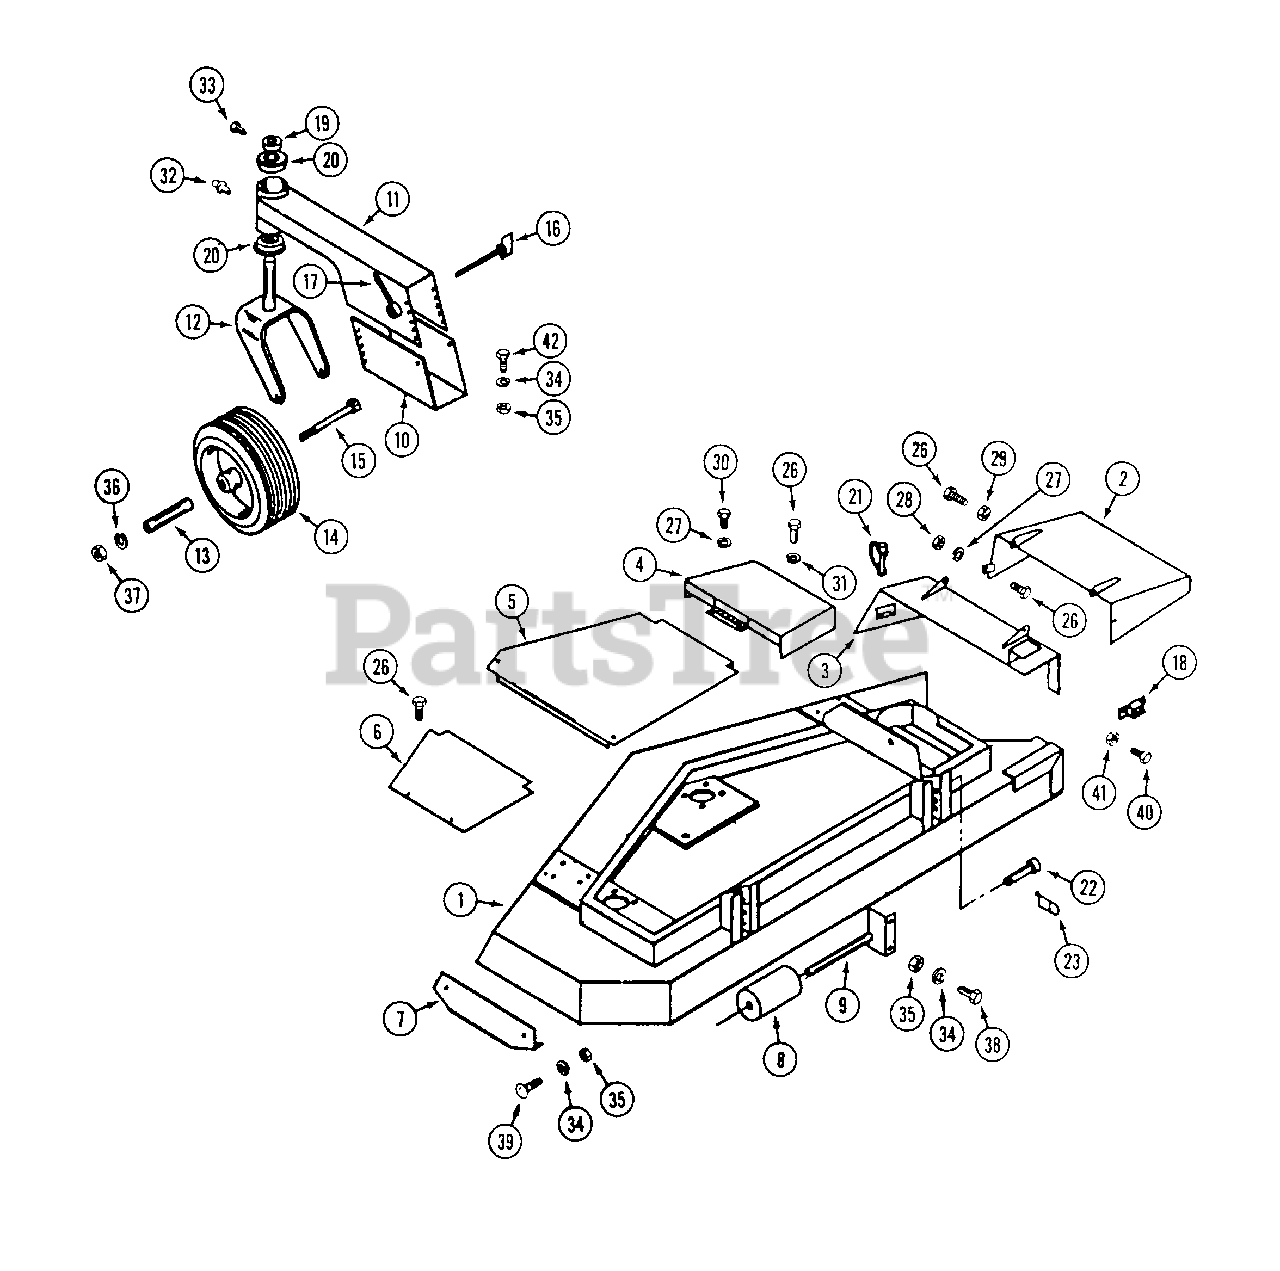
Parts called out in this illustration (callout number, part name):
2	CHUTE - foot guard
3	MOUNT - foot guard
4	COVER - pulley
5	COVER - center
8	ROLLER - anti-scalp
9	SHAFT - roller
10	BRACKET - gauge wheel mount
11	MOUNT - gauge wheel
13	AXLE - wheel
15	BOLT - 1/2" - 13 x 6-1/2"
17	NUT - gauge wheel handle
18	BREAKER - circuit, 10 amp.
21	PIN - "fas-tatch"
23	PIN - cotter, hair
26	BOLT - 1/4" - 20 x 3/4"
27	LOCKWASHER - 1/4"
28	NUT - 1/4" - 20
29	NUT - 1/4" - 20 lock
30	BOLT - 1/4" - 20 x 1"
31	WASHER - 1/4"
32	FITTING - grease
33	SCREW - set 5/16" - 18 x 1/2" square head
34	LOCKWASHER - 5/16"
35	NUT - 5/16" - 18
36	LOCKWASHER - 1/2"
37	NUT - 1/2" - 13
38	BOLT - 5/16" - 18 x 3/4"
39	BOLT - 5/16" - 18 x 3/4" carriage
40	SCREW - #10 - 32 x 1/2"
41	NUT - #10 - 32
42	BOLT - 5/16" - 18 x 1" carriage
